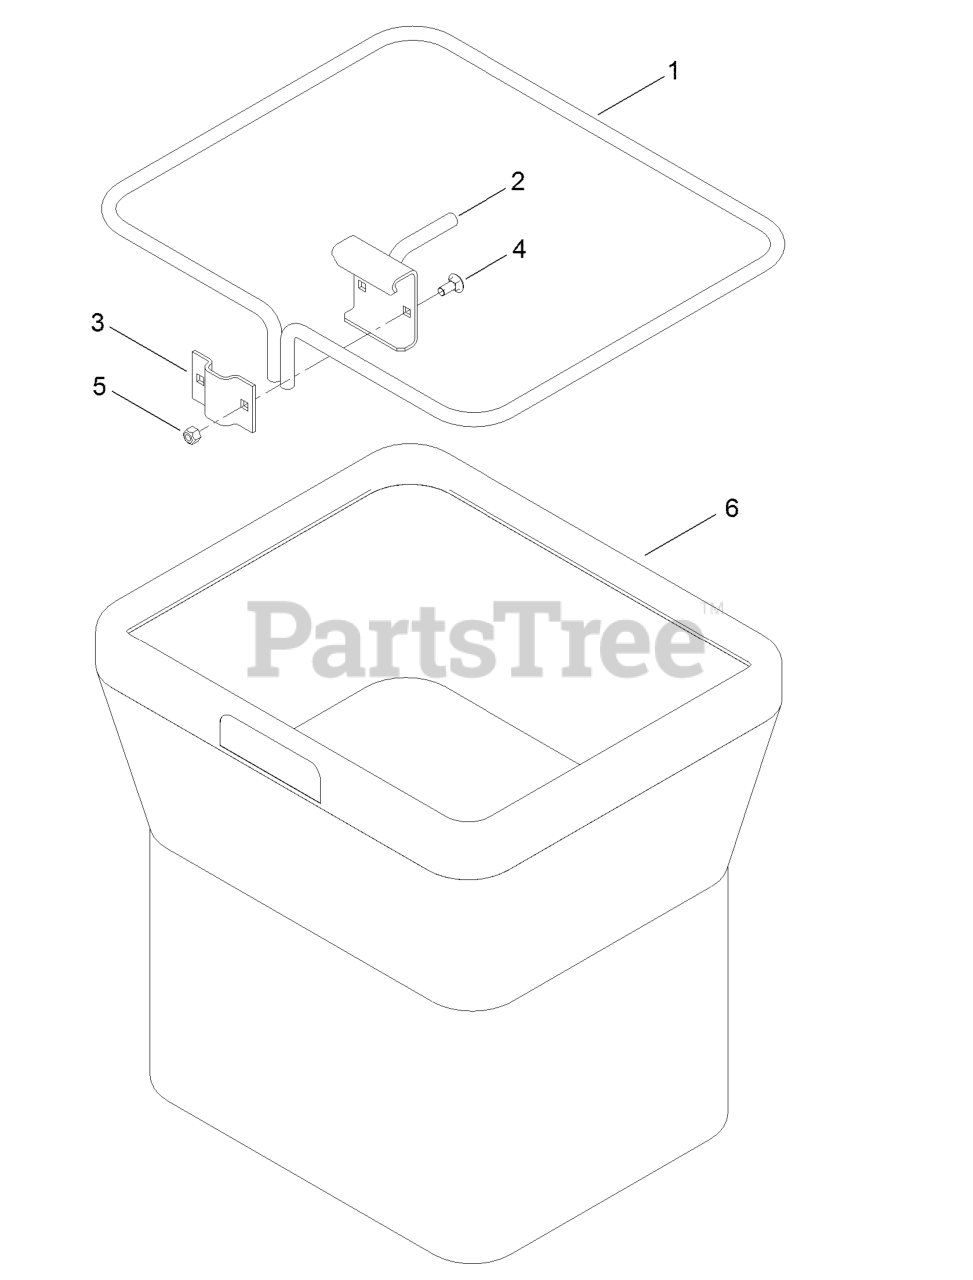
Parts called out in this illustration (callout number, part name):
1	FRAME-BAG
4	BOLT-CARR
5	NUT-LOCK, NI
